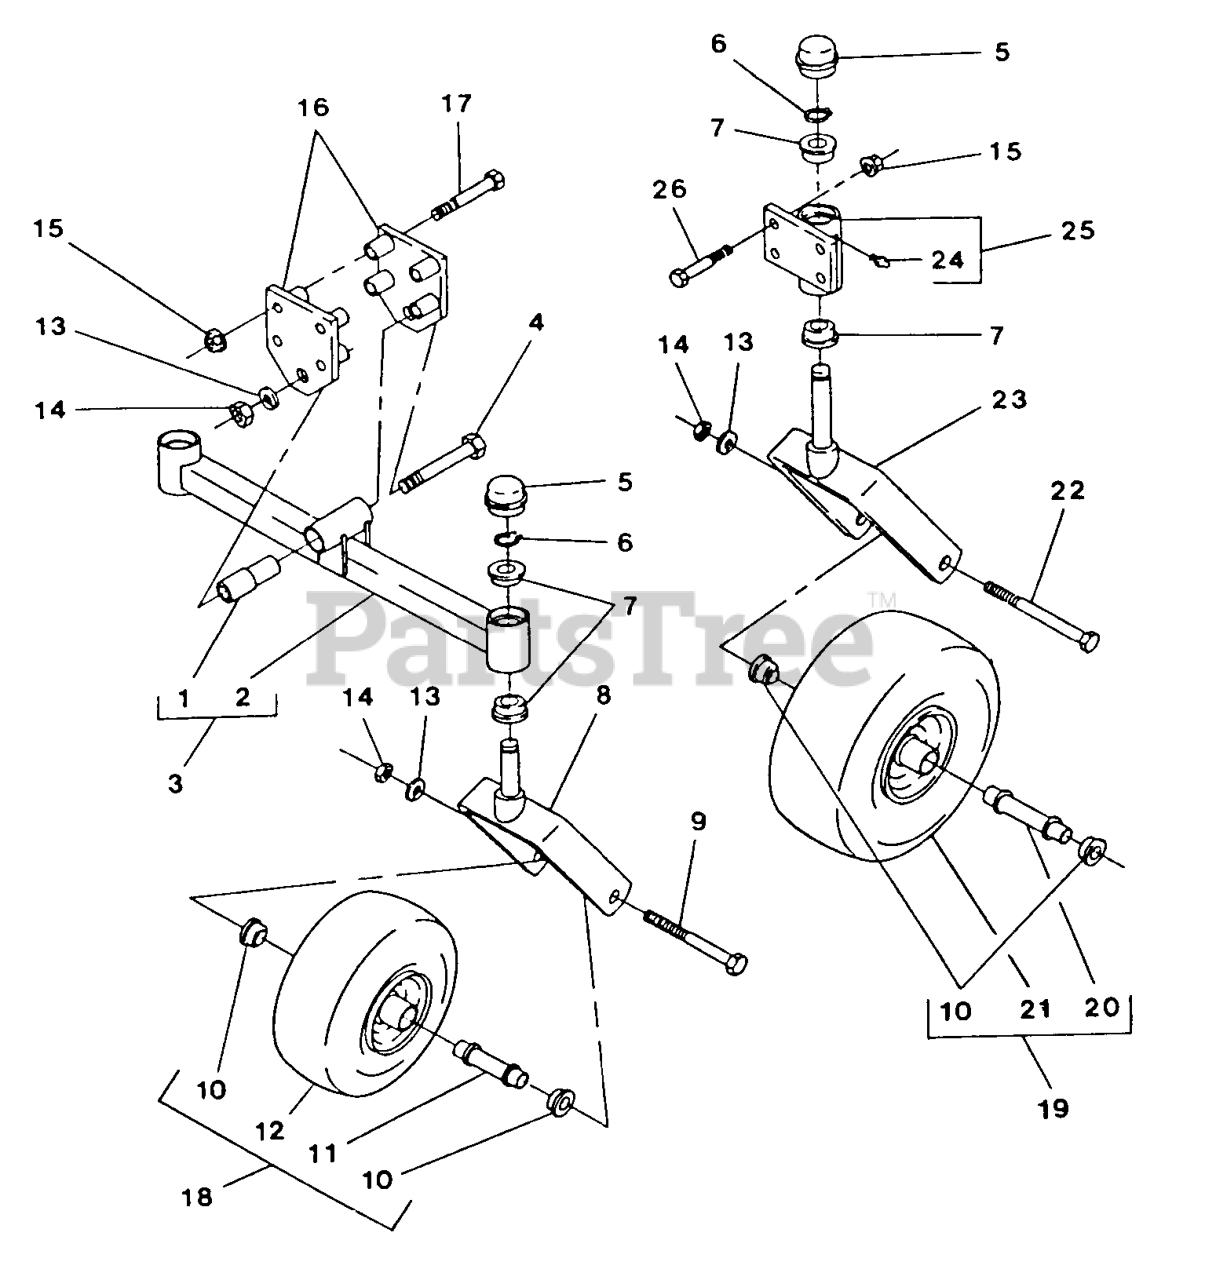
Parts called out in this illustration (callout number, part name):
5	CAP,GREASE
7	BEARING,FLANGED
11	WLD,WHEEL SPACER
18	ASM,CASTER WHEEL
20	SPACER WLDMT,WHEEL
23	WLD,CASTER FORK
25	WLD,CASTER MOUNT
